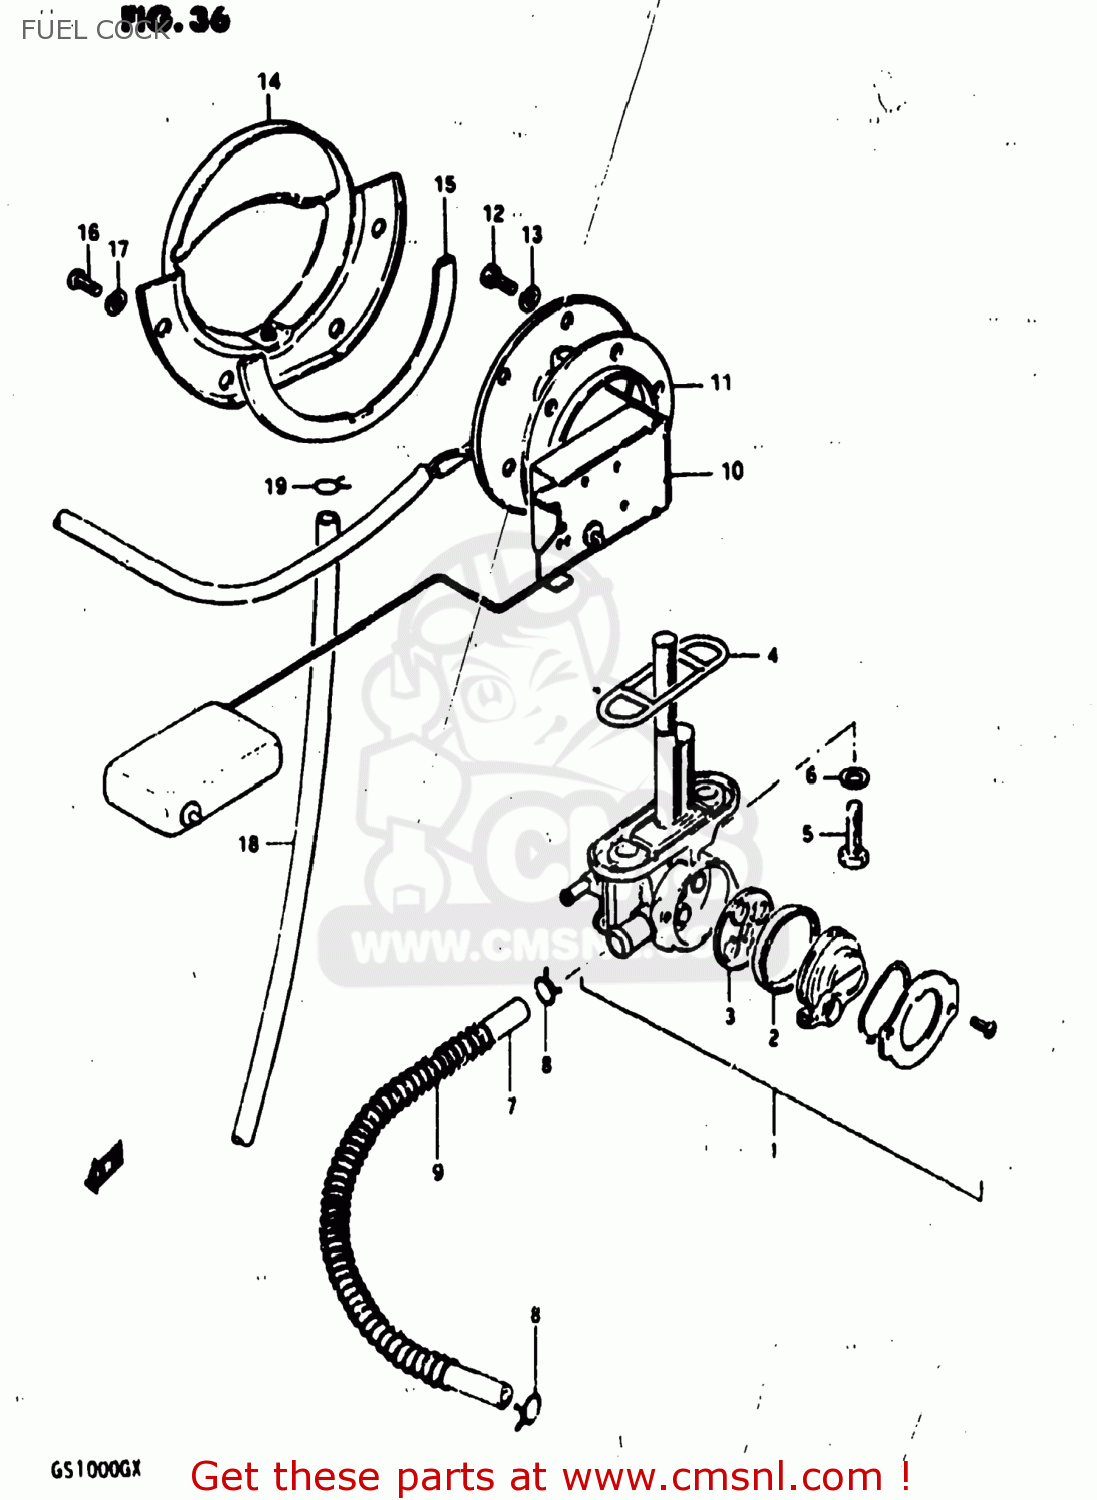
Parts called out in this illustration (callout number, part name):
1	COCK ASSY,FUEL
2	V SEAL,FUEL COCK
3	GASKET (NAS)
4	GASKET, FUEL COCK (NAS)
5	BOLT(6X20)
6	GASKET
7	HOSE
8	CLIP
9	SPRING
10	GAUGE ASSEMBLY,FUEL LEVEL
11	GASKET,FUEL LEVEL GAUGE (NAS)
12	BOLT
13	LOCK WASHER
14	PLATE,FUEL DRAIN
15	GASKET,FUEL DRAIN PLATE (NAS)
16	SCREW
17	LOCK WASHER
18	HOSE,FUEL
19	CLIP
